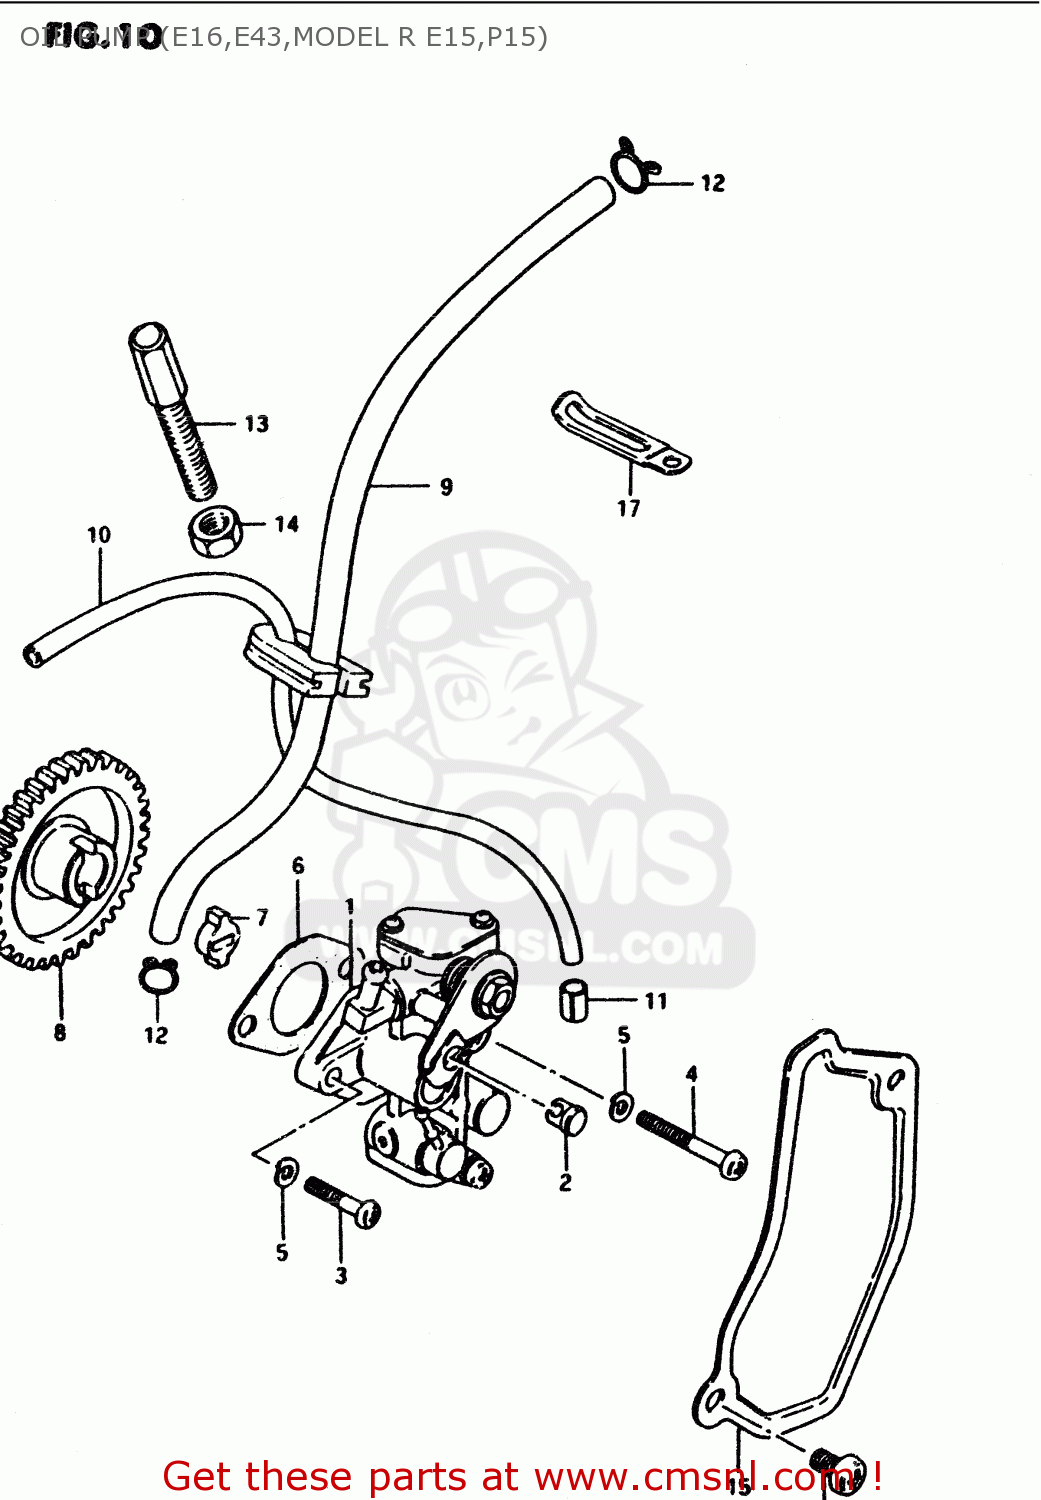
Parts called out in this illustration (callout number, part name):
1	PUMP ASSY,OIL
2	TERMINAL,CABLE
3	SCREW
4	SCREW
5	LOCK WASHER
6	GASKET,OIL PUMP (NAS)
7	PIECE,OIL PUMP DRIVE
8	GEAR,OIL PUMP DRIVE
9	HOSE (4.5X8.5X600)
10	HOSE,NO.2
11	CLIP
12	CLIP
13	BOLT
14	NUT
15	CAP,OIL PUMP INSPECTION
16	SCREW
17	CLAMP
